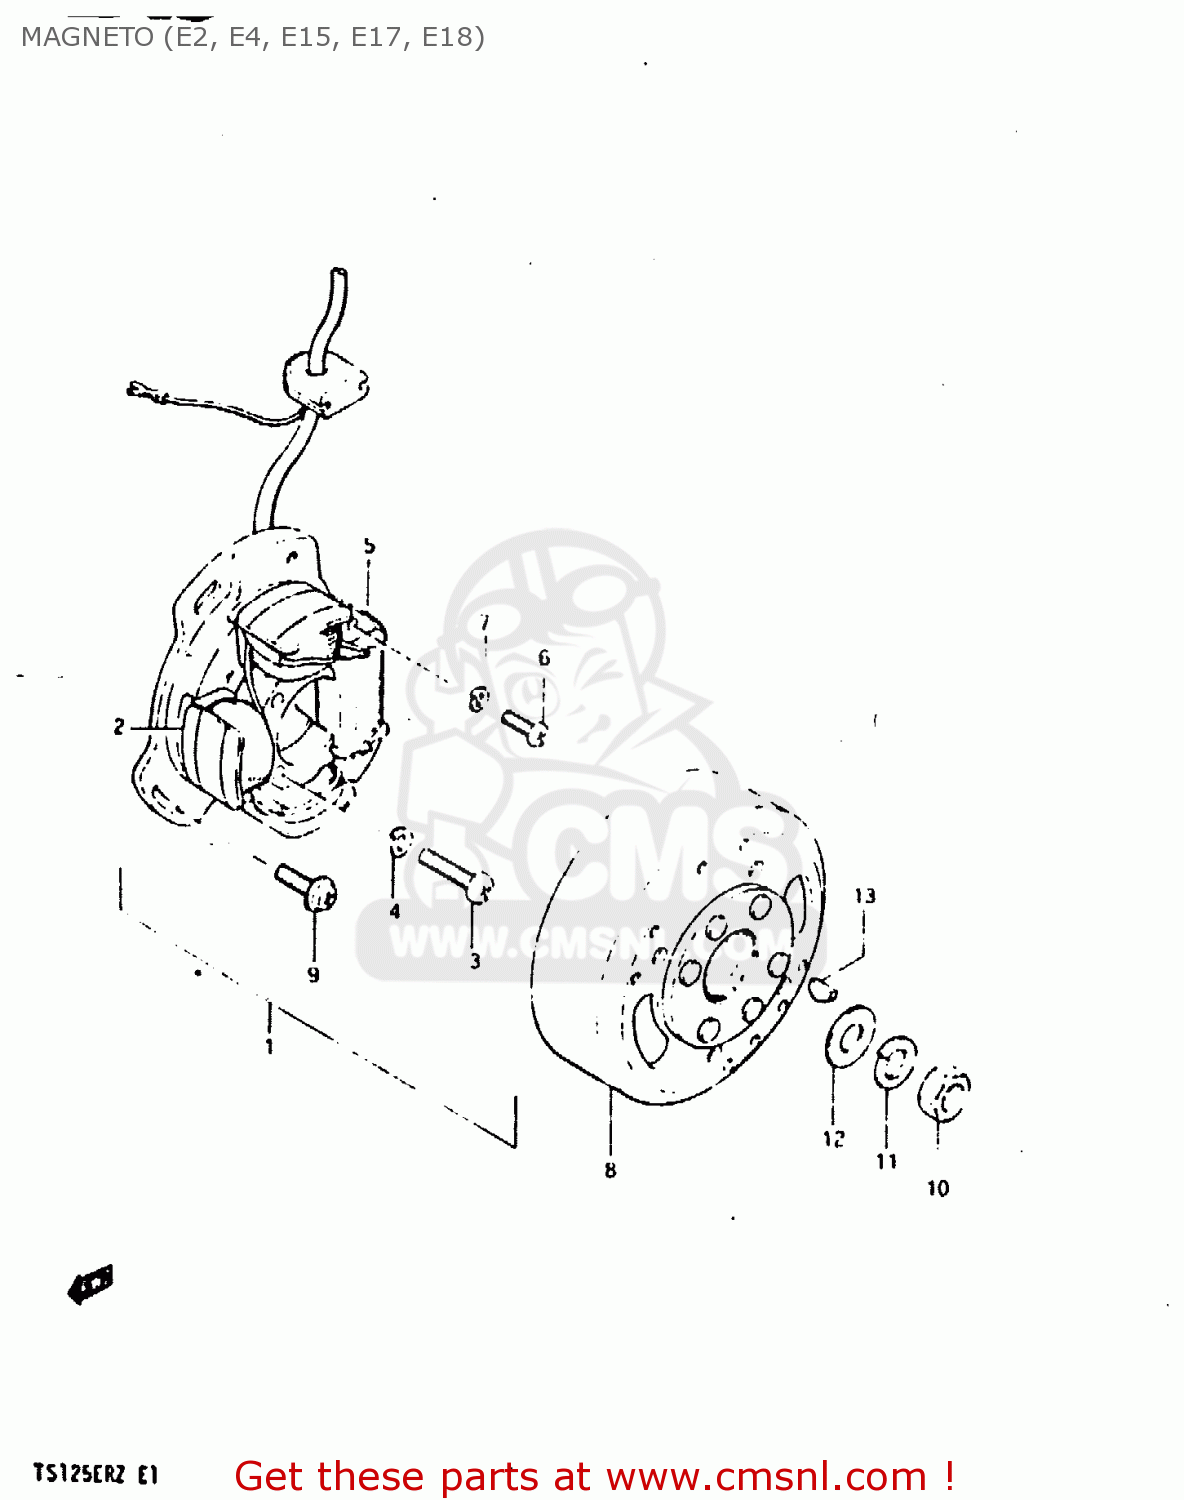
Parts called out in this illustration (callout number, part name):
1	STATOR, ASSY
2	COIL,STARTER
3	SCREW 6X30
4	LOCK WASHER
5	COIL
6	SCREW
7	LOCK WASHER
8	ROTOR
9	SCREW(5X14)
10	NUT (10MM)
11	LOCK WASHER
12	WASHER
13	KEY
